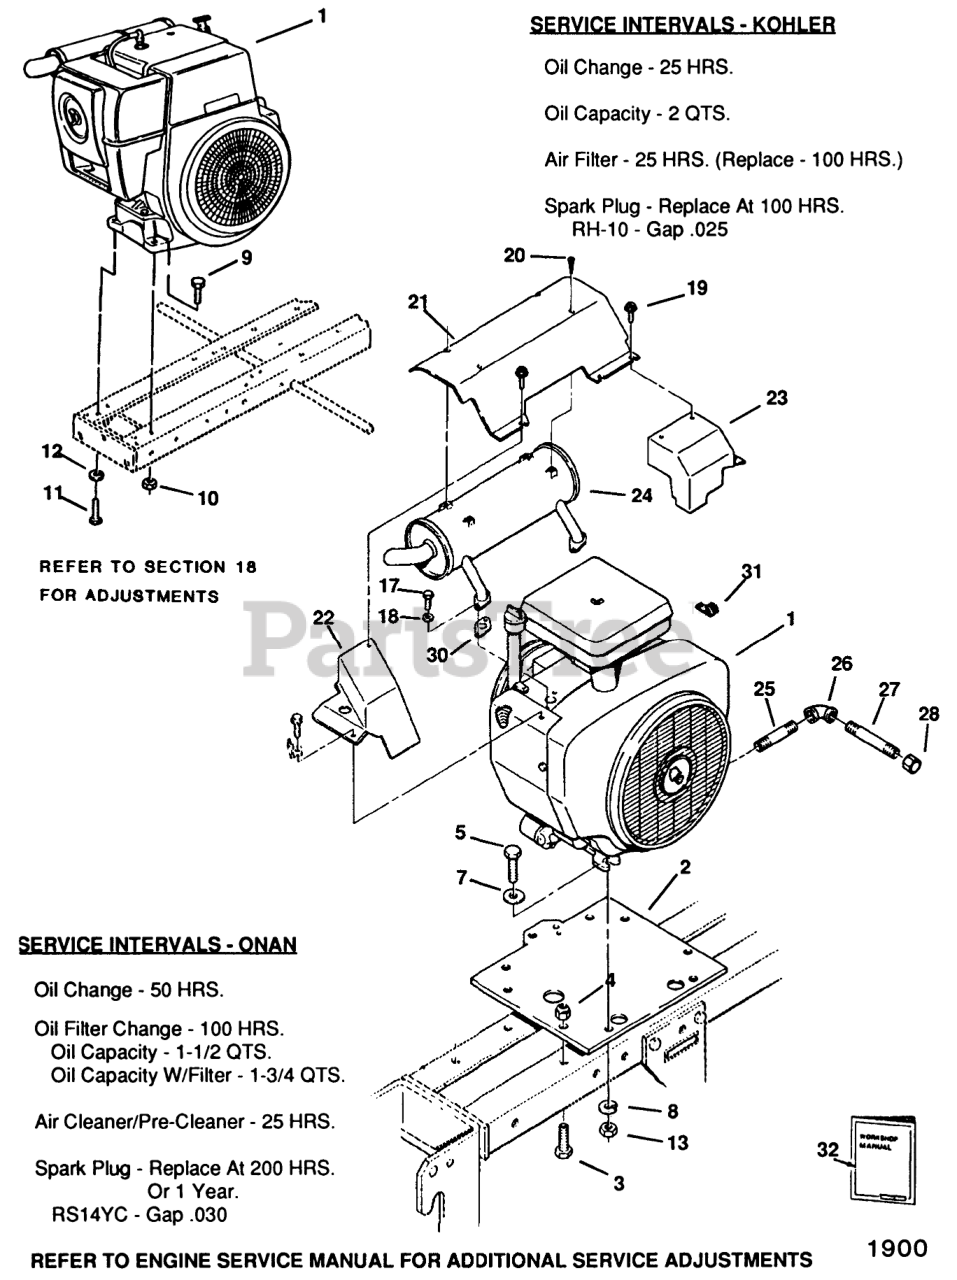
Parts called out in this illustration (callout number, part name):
1	Engine 10HP Kohler M-10-S Spec 461521 (s/n 1919902923 & up)-310
2	PLATE-ENGINE B
3	Bolt
5	Bolt
7	Washer
8	LOCKWASHER
9	BOLT
10	NUT
11	BOLT
12	LOCKWASHER
13	Nut
17	Bolt
18	Lockwasher
19	Bolt
20	Screw
21	Air Deflector
22	LH Exhaust Cover
23	RH Exhaust Cover
24	MUFFLER-EXHAUST
25	Pipe
26	ELBOW 3/8 90 DEG
27	PIPE-NIPPLE 3/8 X 4"
28	Cap
30	Exhaust Gasket
31	J-CLIP
32	Magnum Kohler Service & Repair Manual
